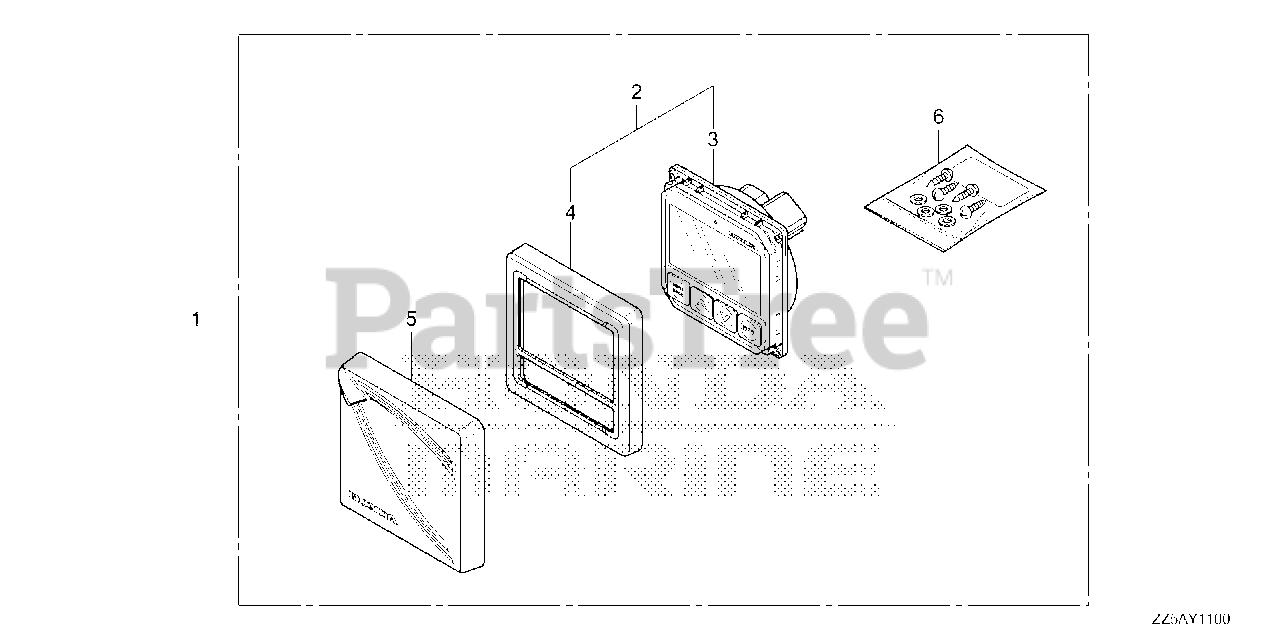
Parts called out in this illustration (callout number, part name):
1	DISPLAY KIT
2	DISPLAY ASSY.
3	DISPLAY UNIT
4	BEZEL, DISPLAY
5	COVER, DISPLAY
6	SCREW SET
